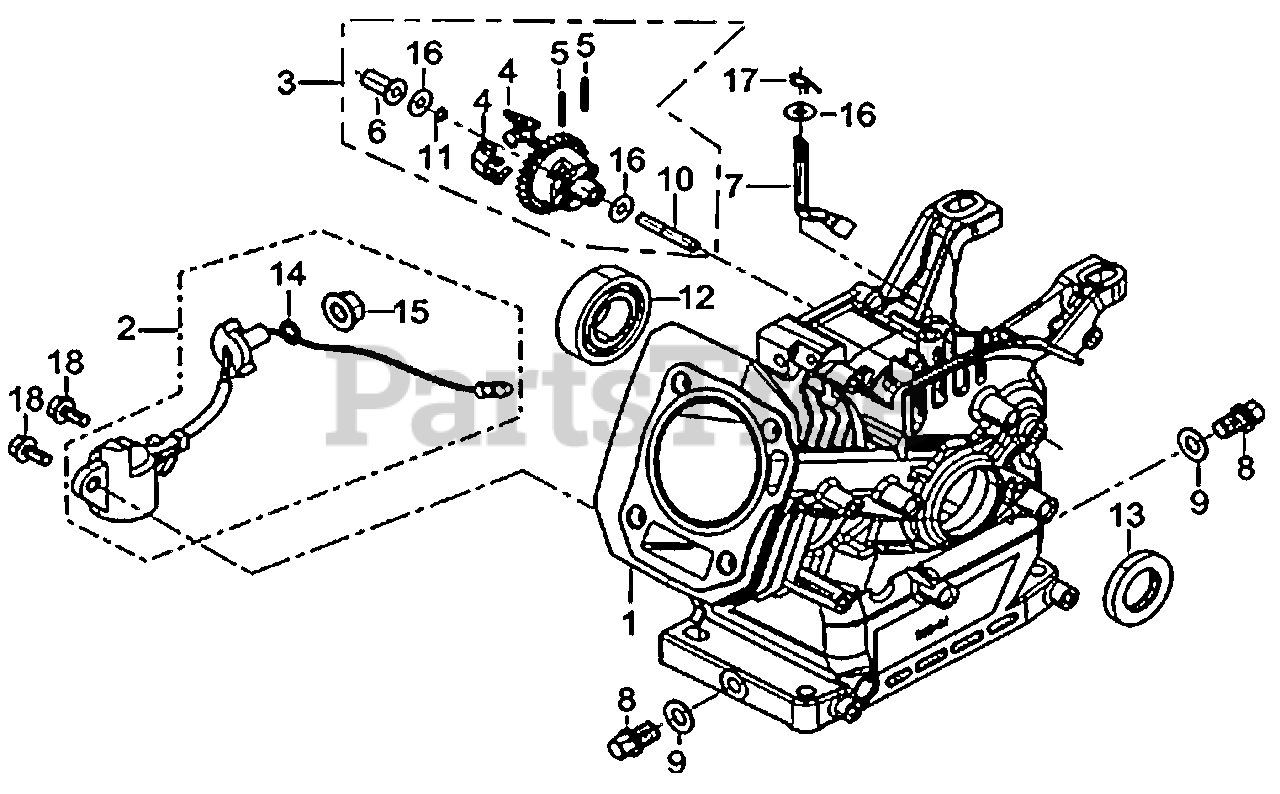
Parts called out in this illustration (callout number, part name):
1	CRANKCASE SUBASSEMBLY.
2	SENSOR, ENGINE OIL
3	GEAR ASSY, GOVERNOR
7	ARM, GOVERNOR
8	BOLT, DRAIN PLUG
13	SEAL, OIL
17	PIN, SPLIT
